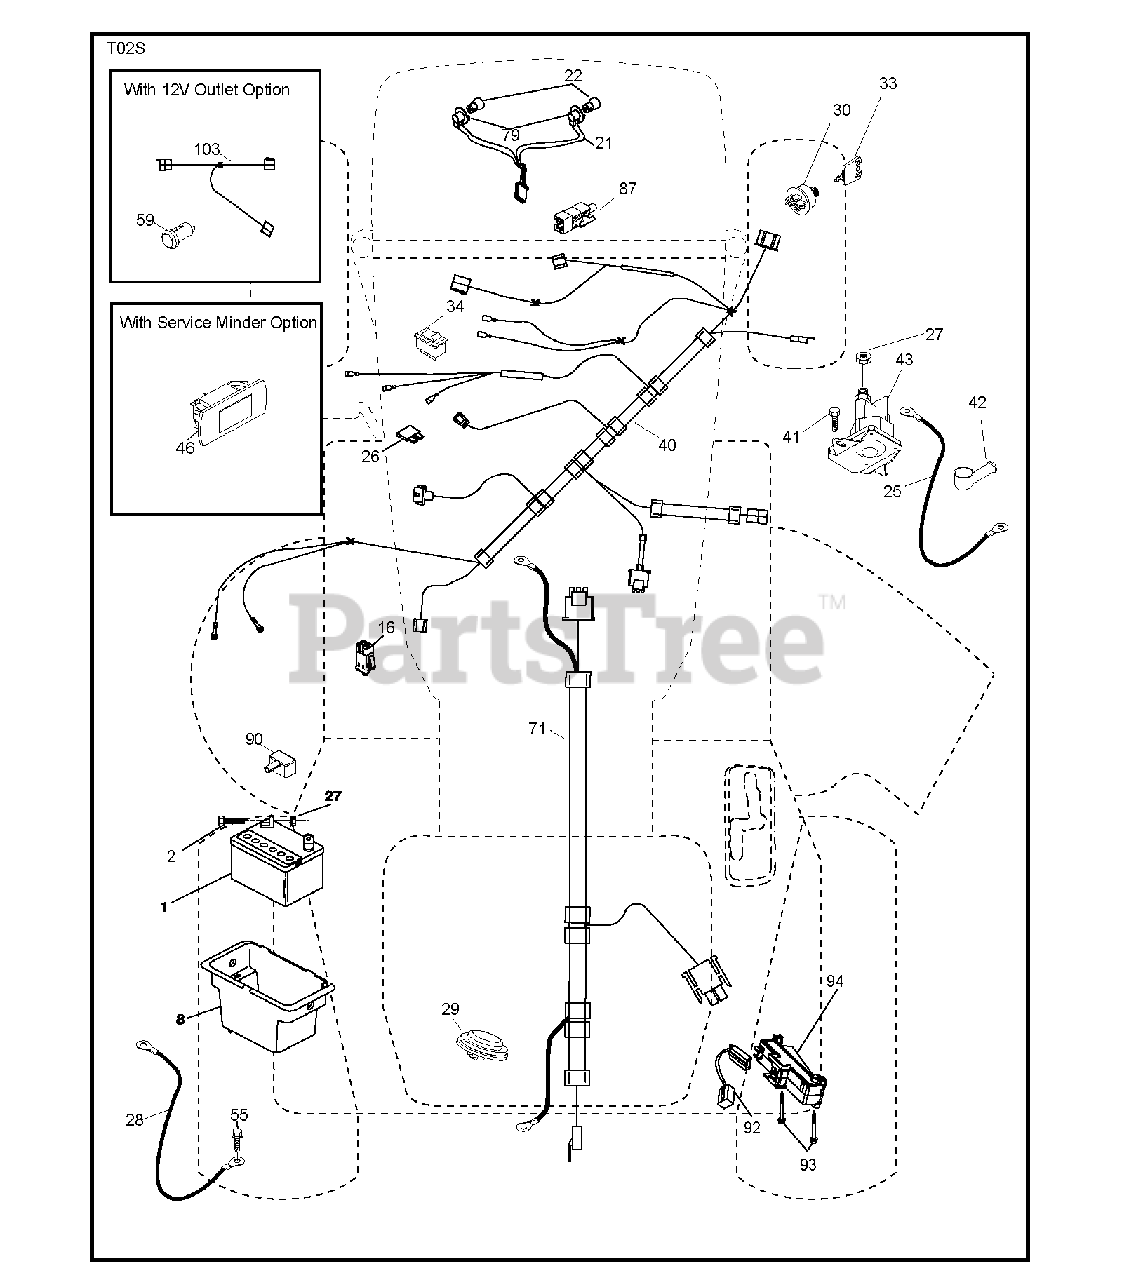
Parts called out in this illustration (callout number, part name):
1	REPL BY 532 12 38-99
8	BOX.BATTERY.MNT.REAR.L
16	SWITCH INTERLOOK PUSH-IN
21	HARNESS.LIGHT W/4152J BULBS
22	LIGHTBULB
25	CABLE.STARTER.6GA.BL/RED.14.
26	FUSE 20AMP
27	NUT
28	CABLE.BLACK.18"REAR.BA
29	SWITCH.SEAT.DELTA.OPC.
30	SWITCH.IGN.DELTA.W.LGH.ROS
33	KEY.CHAIN.BLISTER.PACK.GEN.INT
34	SWITCH LT
40	HARNESS IGN. DASH
41	SCREW
42	TERMINAL COVER
43	SOLENOID.W/BRASS.PLUNG
55	SCREW 5/16"
79	BULB HOLDER ASM.
87	SWITCH.INTRLCK.CLUTCH.
90	COVER.TERMINAL.BATTERY
92	HARNESS.PIGTAIL.CONSLE
93	SCREW.PLASTITE
94	MODULE.REVERSE.ROS
